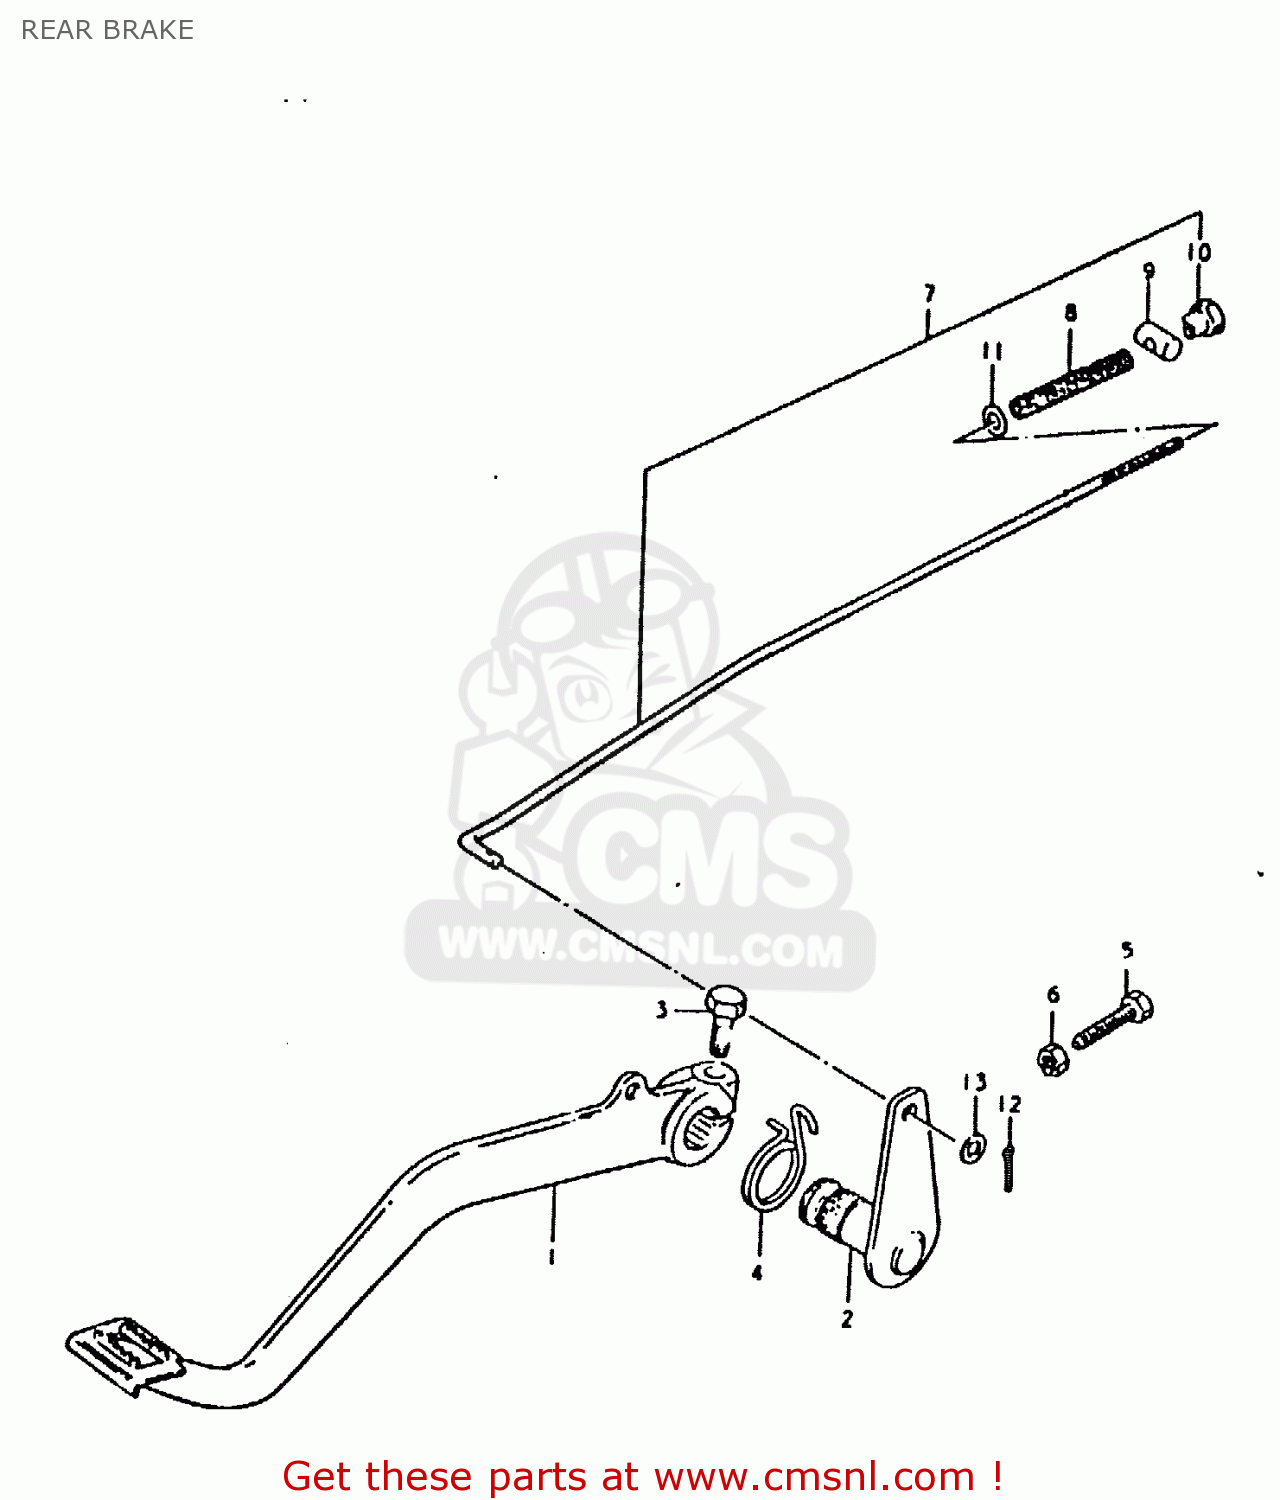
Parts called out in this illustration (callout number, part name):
1	PEDAL, BRAKE
2	ARM,BRAKE PEDAL ROD
3	BOLT
4	SPRING
5	BOLT(6X23)
6	NUT
7	ROD ASSEMBLY,REAR BRAKE
8	SPRING
9	PIN(11X18)
10	NUT
11	WASHER
12	PIN 20X20
13	WASHER
